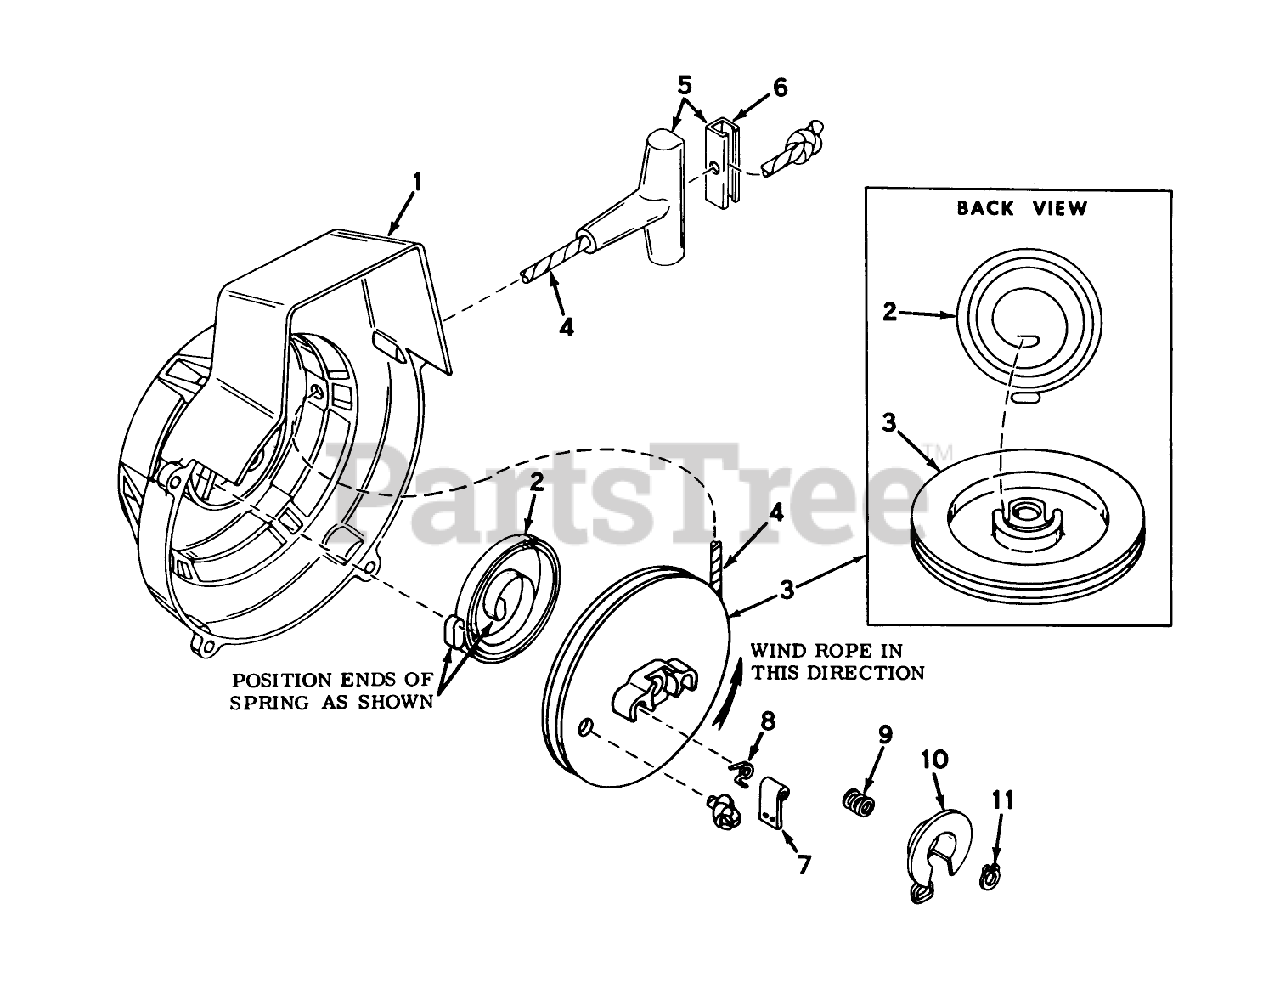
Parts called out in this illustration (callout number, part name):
1	Housing Assy., Shroud Starter
2	Spring, Rewind
3	Pulley, Starter Rope(Incl. No. 8)
4	Rope-Starter
5	Assy., Starter
6	Insert, Handle
7	Dog, Starter
8	Retum Spring, Left Hand Wound
9	Spring, Brake
10	Brake
11	E Ring Truarc
